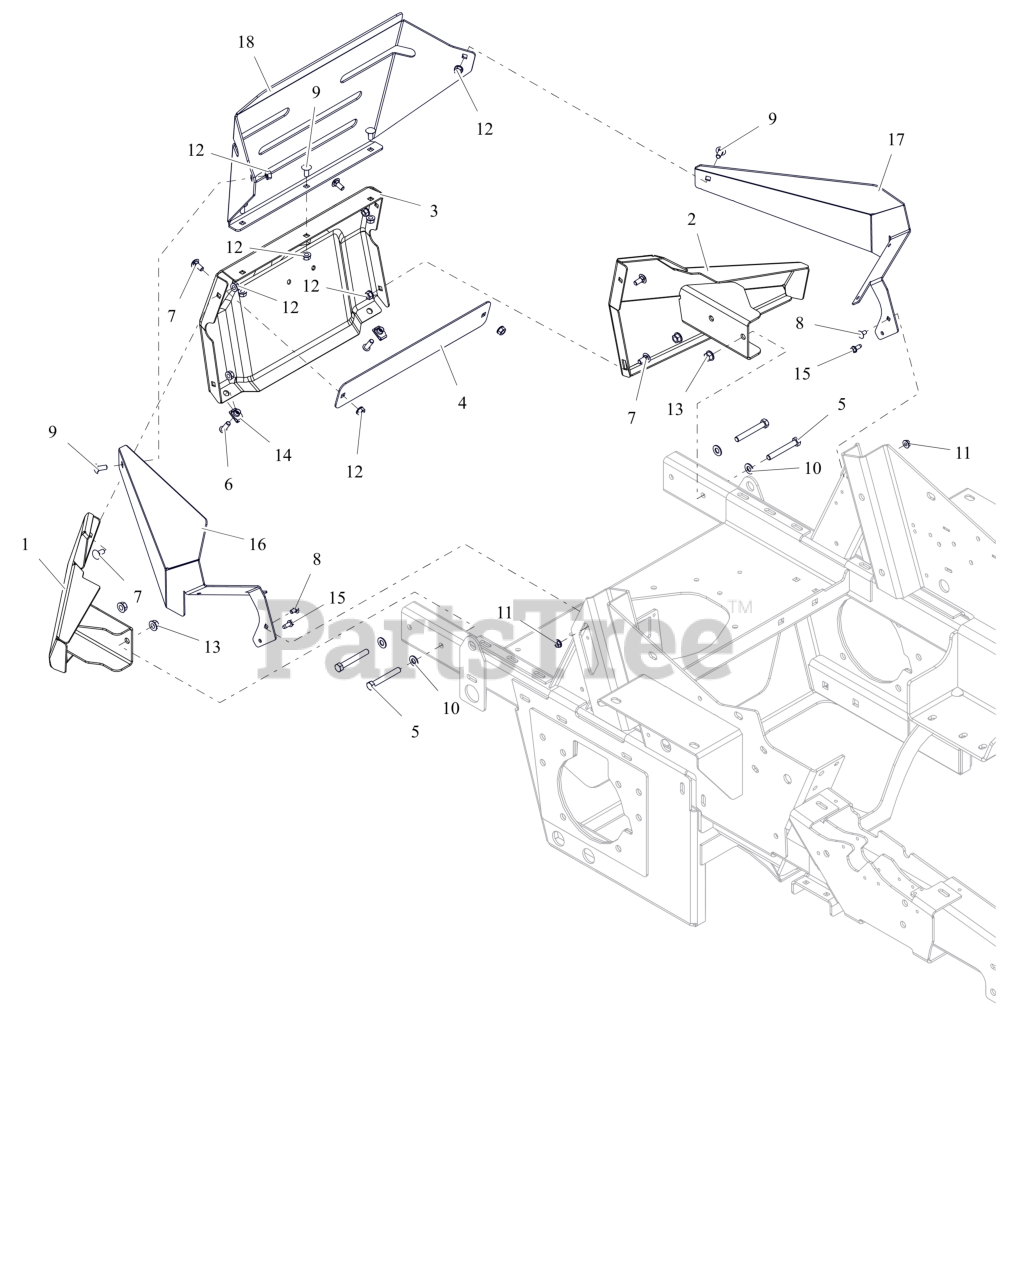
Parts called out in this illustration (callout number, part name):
1	WLDMT, RIGHT REAR BUMPER WING (RED) W/ SAFETY DECALS
2	WLDMT, LEFT REAR BUMPER WING (RED) W/ SAFETY DECALS
3	BUMPER, COMMERCIAL REAR
4	PLATE, BACKER (BLACK)
5	BLT, HEX .38-16X2.75 G5 ZCC
6	BLT,SHCS-BTN .31-18X1.00 ZCC
7	BLT,RHSN .31-18X.75 G5 ZCC
8	BLT, RHSSN.25-20X.500 G5 ZCC
9	BLT, RHSSN.31-18X.750 G5 ZCC
10	WSHR,FLT .406X.812X.065 ZCC
11	NUT-LK-CTR-FLG .25-20 ZC120
12	NUT,LK-CTR-FLG .31-18 GF ZCC
13	NUT-LK-CTR-FLG .375-16 GF ZCC
14	NUT-CLIP RETAINER 5/16-18X.56
15	SCR,TAP .25-20X.625 HWH ZCC
16	BRKT- RH SIDE WRAP MTG
17	BRKT- LH SIDE WRAP MTG
18	WRAP- REAR CENTER
